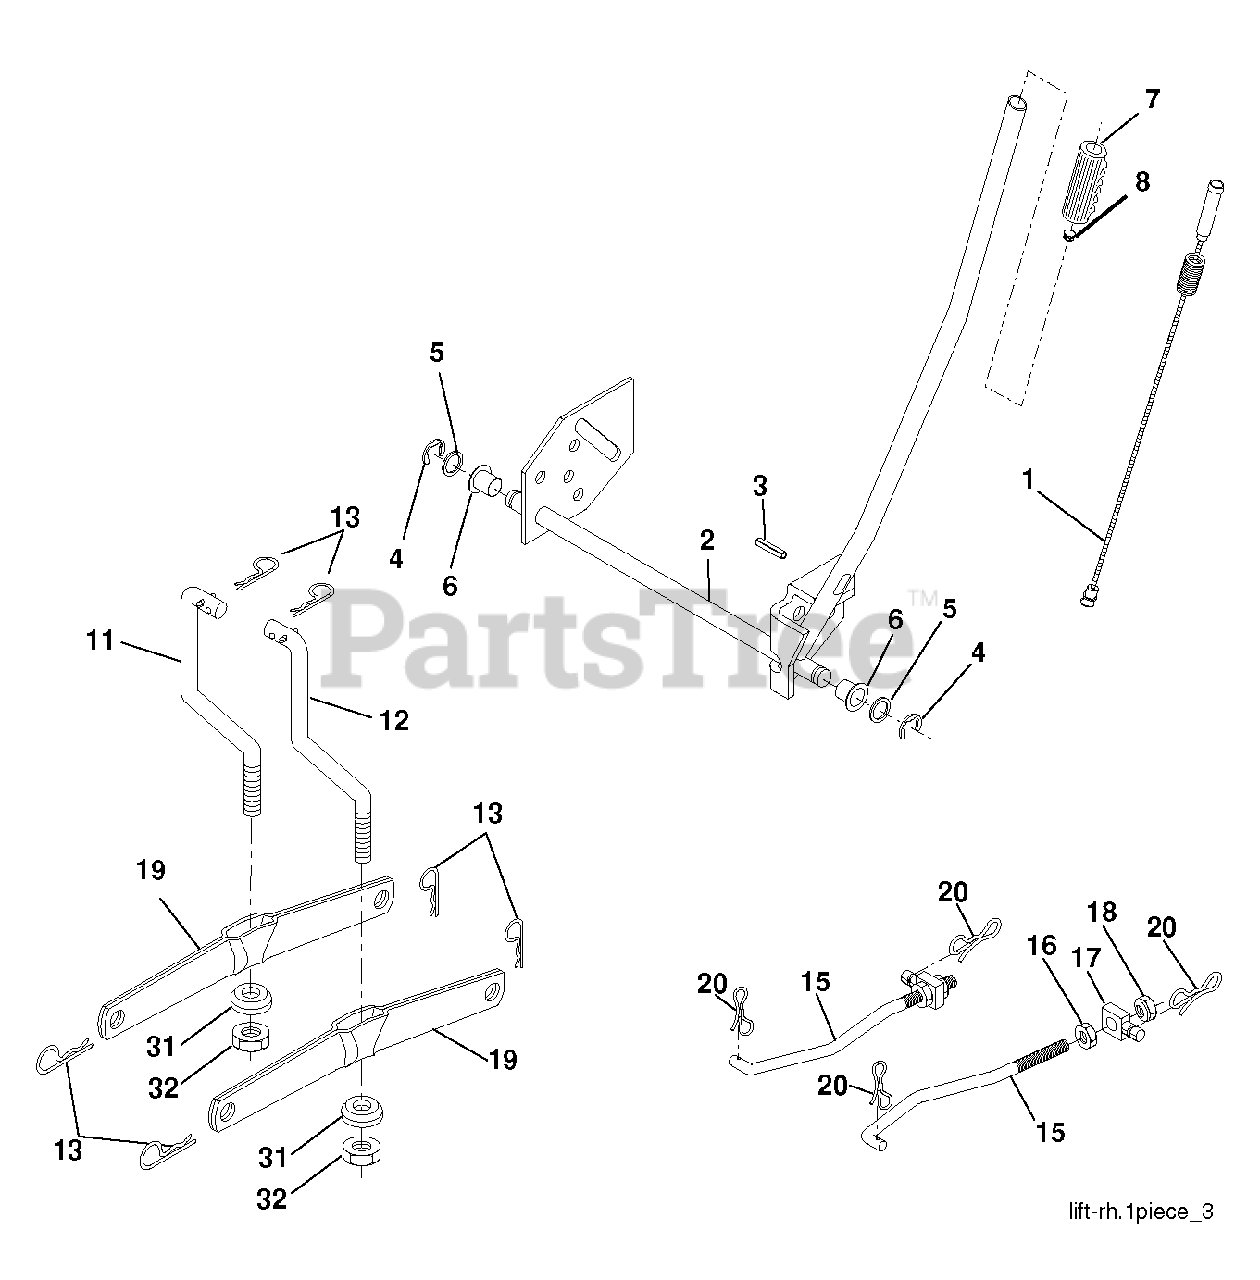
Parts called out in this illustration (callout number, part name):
1	PLUNGER.ASM.LIFT.LVR.BLK.17.32
2	SHAFT ASM R HANDLE
4	RETAINING RING LT
6	BEARING.NYLON
7	GRIP
8	PLUNGER BUT KIT
11	LINK
12	LINK
13	RETAINER-SPRNG RB
15	LINK.SUSPENSION.FRONT
16	NUT
18	NUT
19	ARM.REAR.SUSPENSION
20	PIN.COTTER.7/16.BOW TI
31	BEARING.PIVOT.LIFT
32	NUT CROWNLOCK 3/8-24
